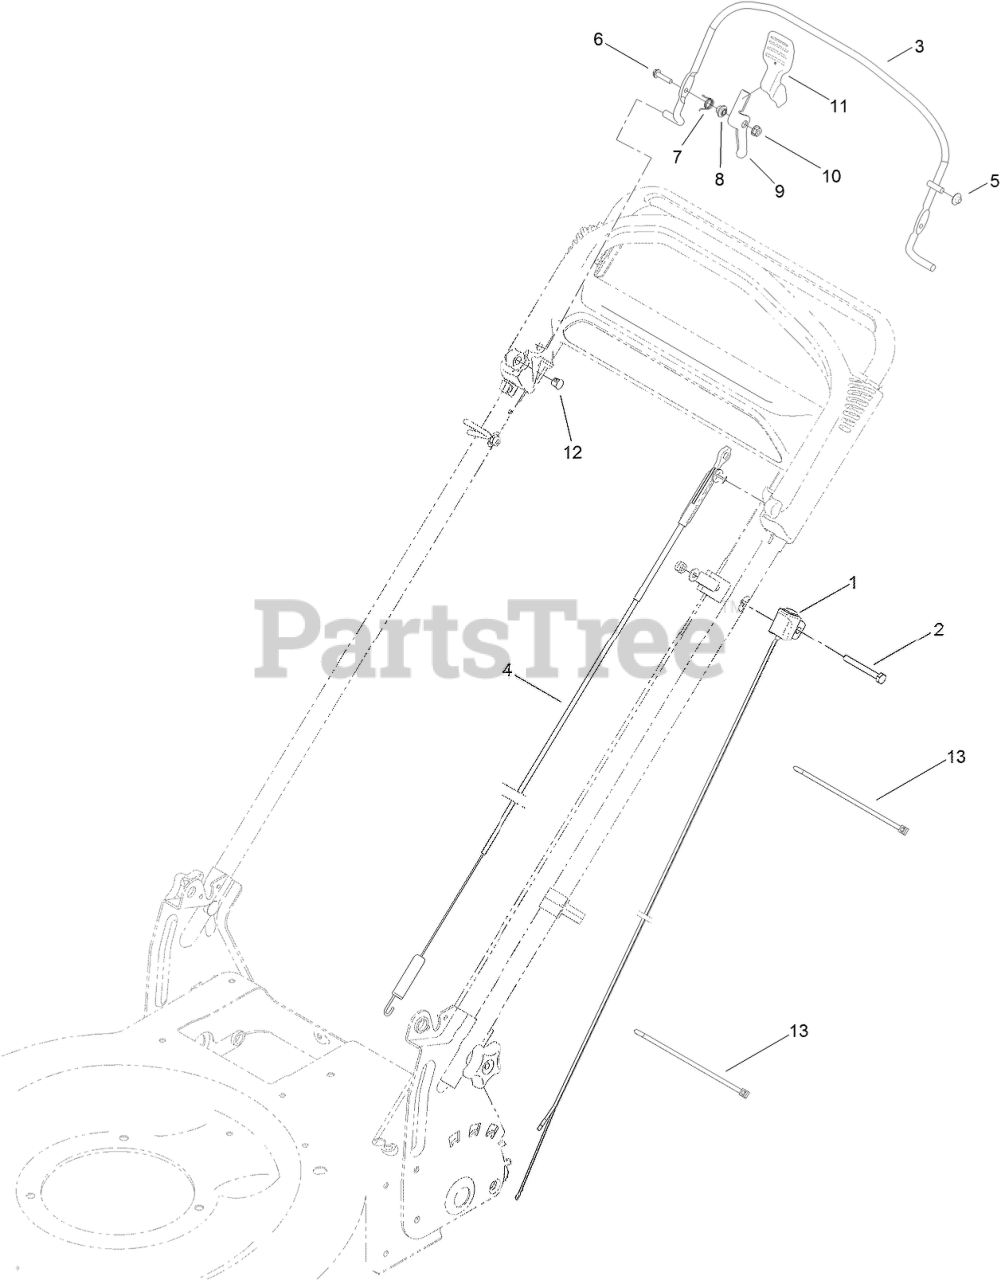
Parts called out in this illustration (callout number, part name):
1	HARNESS
2	SCREW-HH
3	BAIL-BRAKE
4	CABLE-BRAKE
5	NUT-SPEED
6	SCREW-HWH
7	SPRING-TORSION
8	SPACER
9	LEVER
10	NUT-LOCK, FLANGE
12	Plug-Dome
13	TIE-CABLE
